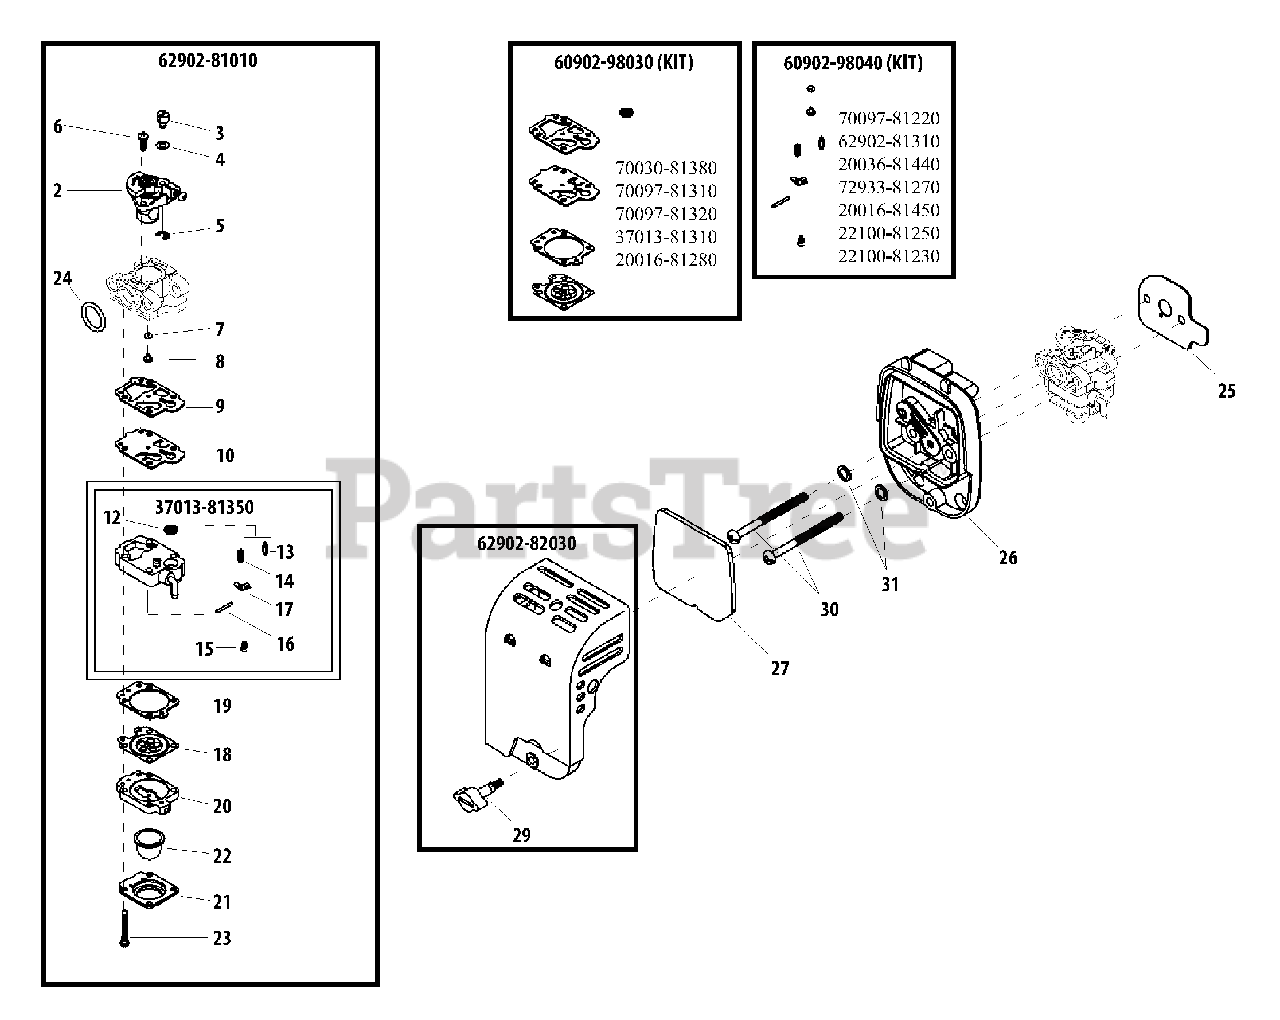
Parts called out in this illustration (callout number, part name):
2	THROTTLE VALVE ASSY
3	SWIVEL
4	WASHER
5	E-RING
6	SCREW, THROTTLE COLLAR
7	O-RING
8	JET, MAIN
9	GASKET, PUMP
10	DIAPHRAGM, PUMP
12	SCREEN, FUEL INLET
13	VALVE, INLET NEEDLE
14	SPRING, METERING LEVER
15	SCREW
16	PIN, METERING LEVER
17	LEVER, METERING
18	DIAPHRAGM, METERING
19	GASKET, METERING DIAPHRAGM
20	BODY ASSY, PURGE
21	RETAINER, PURGE BULB
22	BULB, PURGE
23	SCREW
24	O-RING 15
25	GASKET, INTAKE
26	CASE, AIR FILTER
27	FILTER, AIR
29	THUMBSCREW M5
30	SCREW M5×60
31	WASHER 5 MM
37013-81350	BODY ASSY, PUMP
60902-98030	GASKET / DIAPHRAGM KIT
60902-98040	VALVE KIT, INLET NEEDLE
62902-81010	CARBURETOR
62902-82030	COVER ASSY, AIR FILTER
